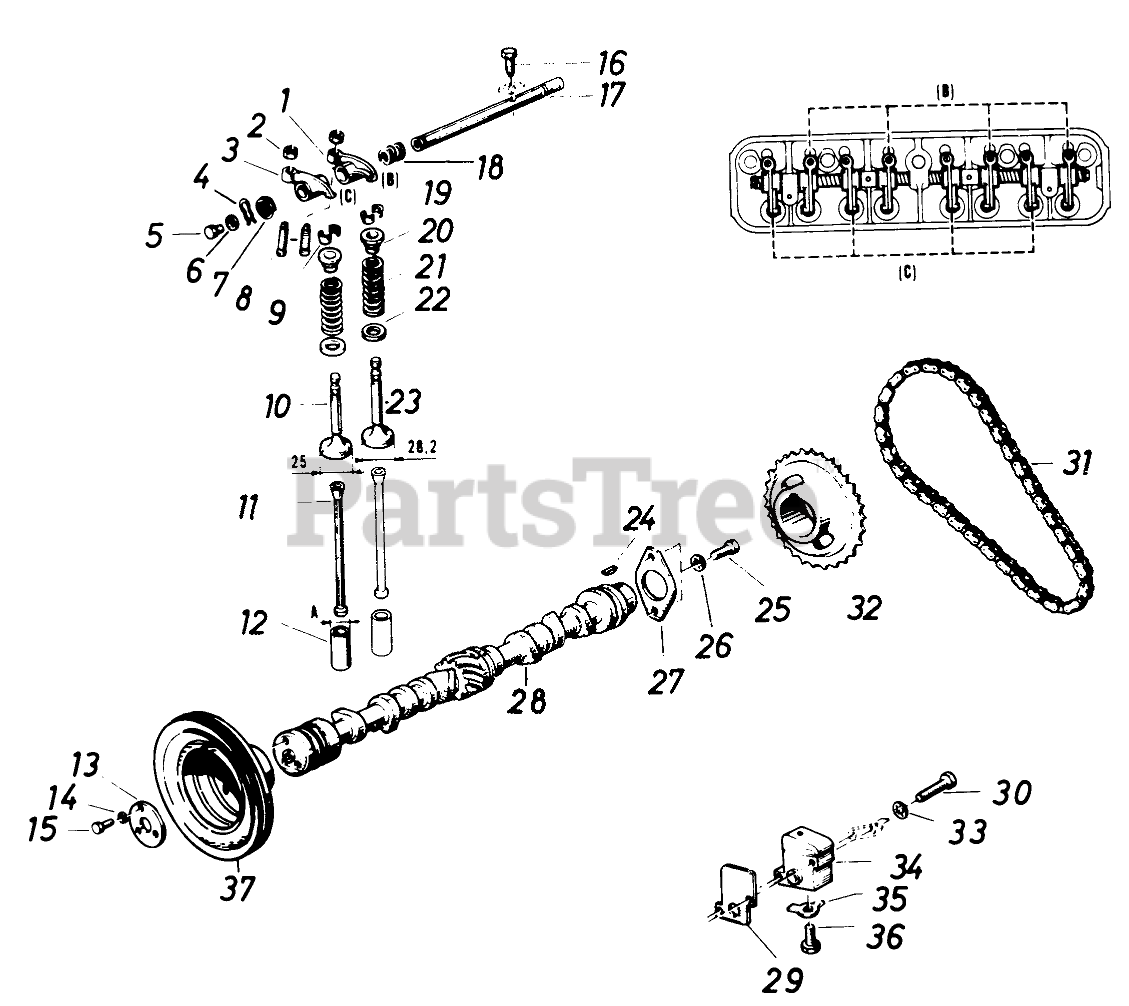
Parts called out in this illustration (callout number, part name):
1	Rocker Arm, Front
3	Rocker Arm, Rear
4	Spring
6	Gasket
7	Spring
8	Adjusting Screw
9	Valve Collets
10	Outlet Valve
11	Push Rod
12	Tappet A19
13	Washer
14	Lockwasher
15	Screw
16	Screw
17	Rocker Arm Shaft
18	Spring
19	Keeper
20	Valve Spring Retainer
21	Valve Spring
22	Washer
23	Inlet Valve
25	Screw
26	Lock Washer
27	Flange
28	Camshaft
29	Lock Plate
30	Screw
31	CHAINE
32	Chain Wheel
33	Washer
34	Chain Adjuster
35	Washer
36	Screw
37	Pulley
